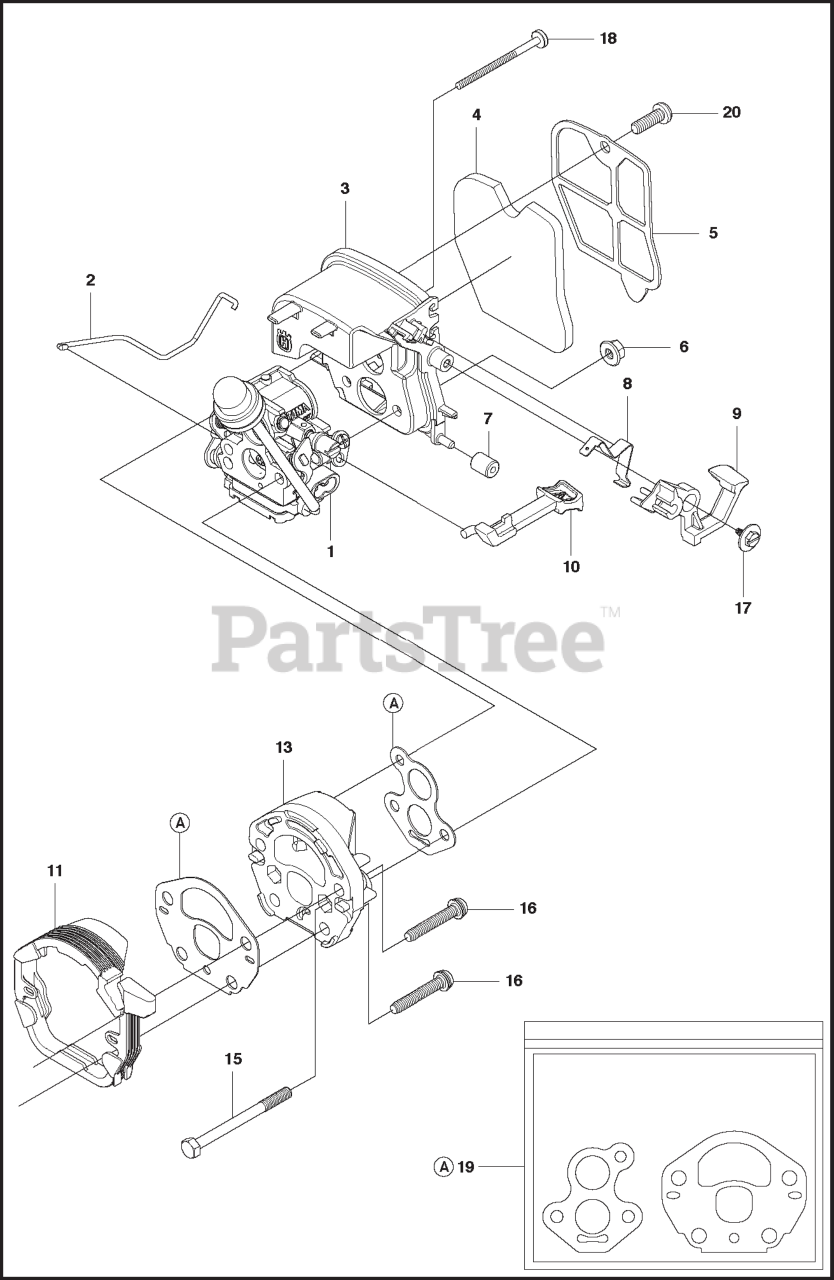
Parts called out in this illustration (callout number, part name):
1	CARBURETTOR 14MM AIR BORE, ANG
2	THROTTLE WIRE
3	AIR FILTER HOUSING BLACK
4	AIR FILTER
5	PLATE
6	NUT
7	ISOLATOR FILTER HOUSING
8	SPRING
9	SWITCH LEVER
10	CHOKE KNOB
11	CARB ADAPTOR SEAL
13	ADAPTOR CARBURETOR
15	STUD CARBURETOR
16	SCREW
17	SCREW
18	TOP STUD - CARBURETOR
19	GASKET KIT
20	SCREW FILTER PLATE
